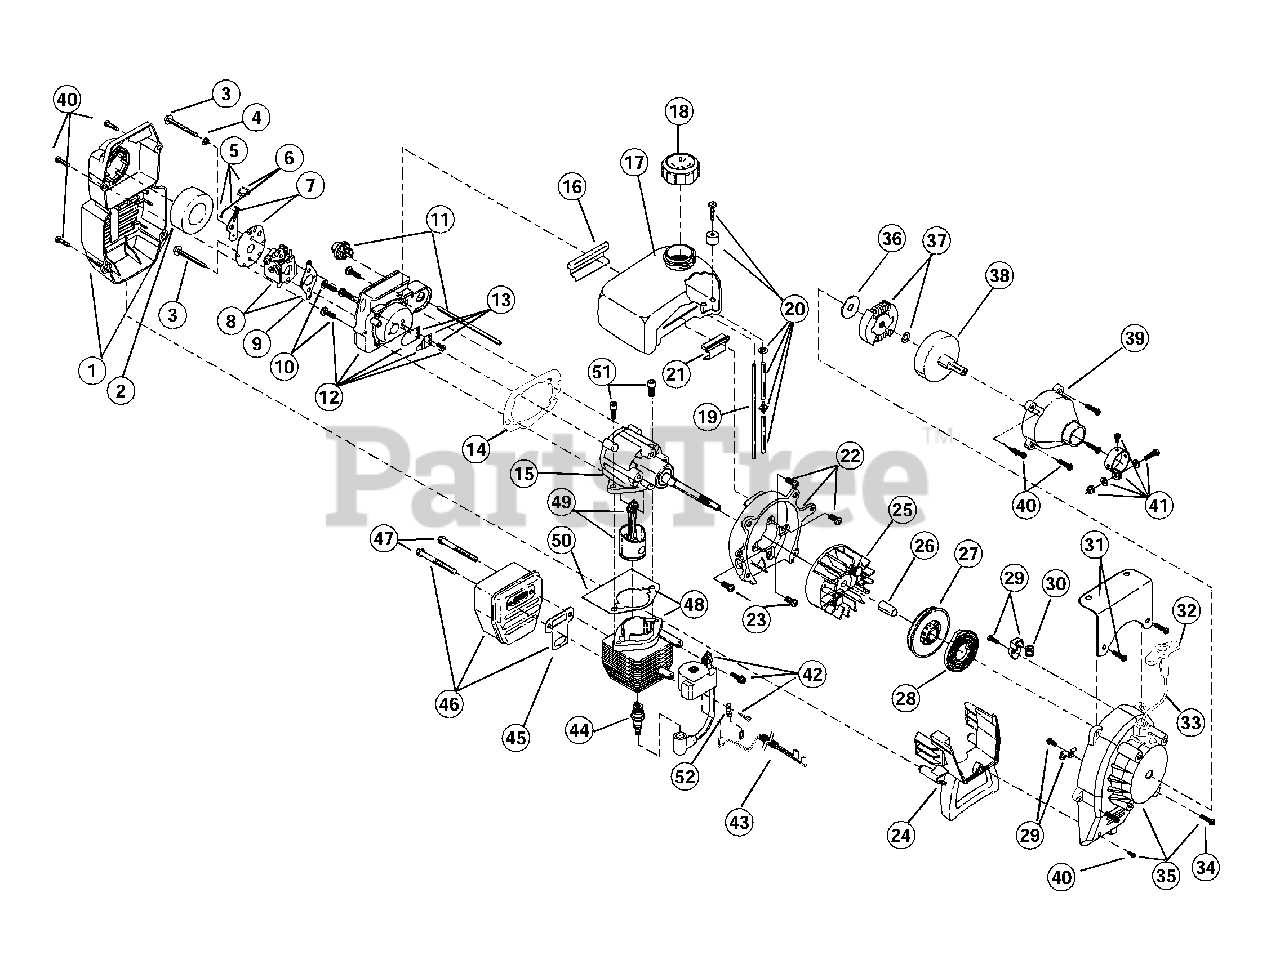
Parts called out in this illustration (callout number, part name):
1	Air Cleaner/Muffler Cover Assembly
2	Air Cleaner Filter
3	Carburetor Mounting Screw Assembly
4	Wavey Washer
5	Choke Lever Assembly
6	Choke Knob and Screw
7	Choke Lever and Plate
8	Carburetor Assembly
9	Carburetor Gasket
10	Carb Mount Screw
11	Primer and Hose Assembly
12	Carb Mount Assembly
13	Reed Assembly
14	Carburetor Mount Gasket
15	Crank Case Service Assembly
16	Rear Mounting Pad
17	Fuel Tank Assembly
18	Fuel Cap Assembly
19	Fuel Return Line
20	Fuel Line Assembly
21	Front Mounting Pad
22	Shroud Assembly
23	Shroud Screw
24	Shroud Extension and Stand
25	Flywheel Assembly
27	Recoil Pulley Assembly
28	Recoil Spring
29	Pulley Retainer Assembly
30	Rope Guide
31	Fuel Tank Guard Assembly
32	Pull Handle
34	Housing Screw
35	Starter Housing Assembly
36	Clutch Washer
37	Clutch Rotor Assembly
38	Clutch Drum Assembly
39	Clutch Cover Assembly
40	Clutch Cover Screw
41	Upper Clamp Assembly
42	Module Assembly
43	Wire Lead
44	Spark Plug
45	Exhaust Gasket
46	Muffler Assembly
47	Muffler Mounting Bolt Assembly
48	Cylinder Assembly
49	Piston and Rod Assembly
50	Cylinder Gasket
51	Cylinder Bolt
52	Ground Tab
